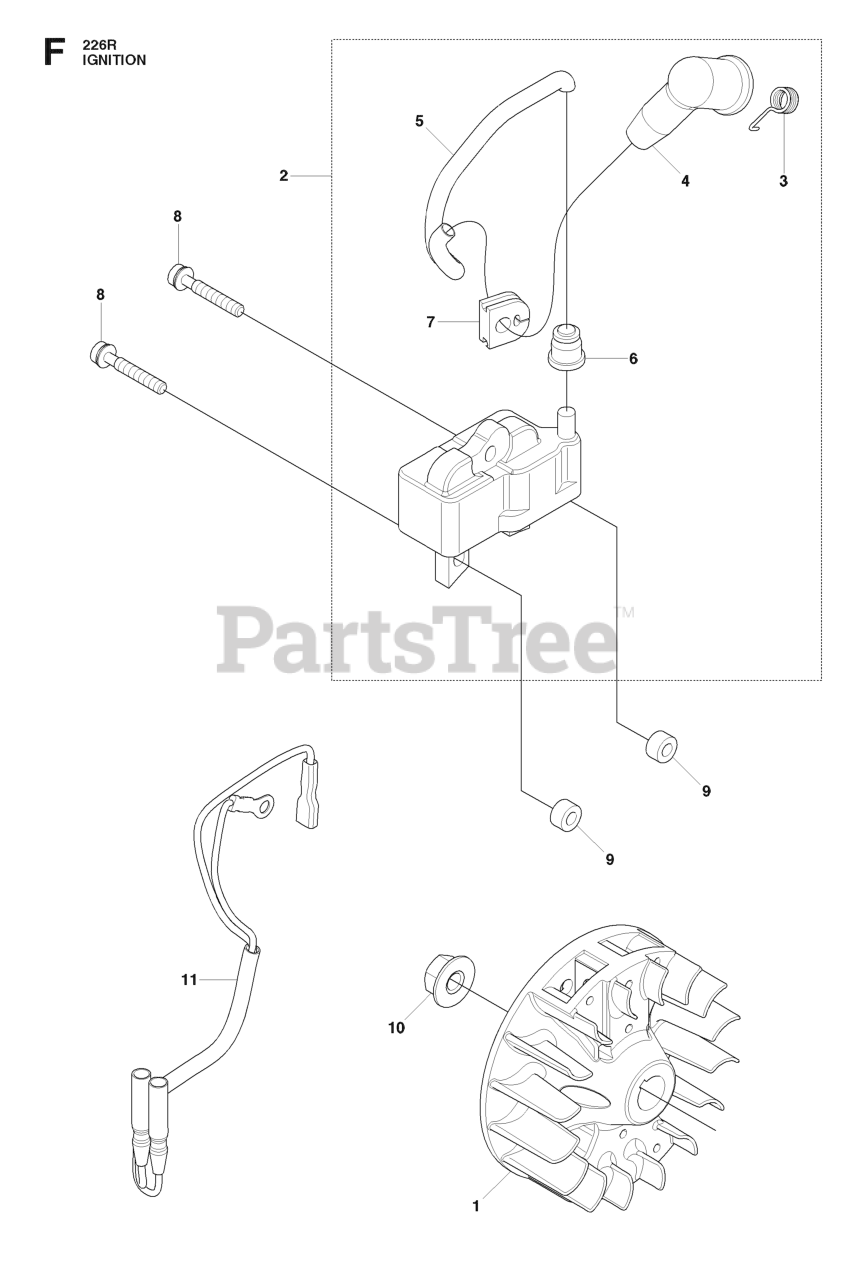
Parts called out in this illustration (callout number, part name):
3	SPRING
6	CAP
9	SPACER
10	NUT
